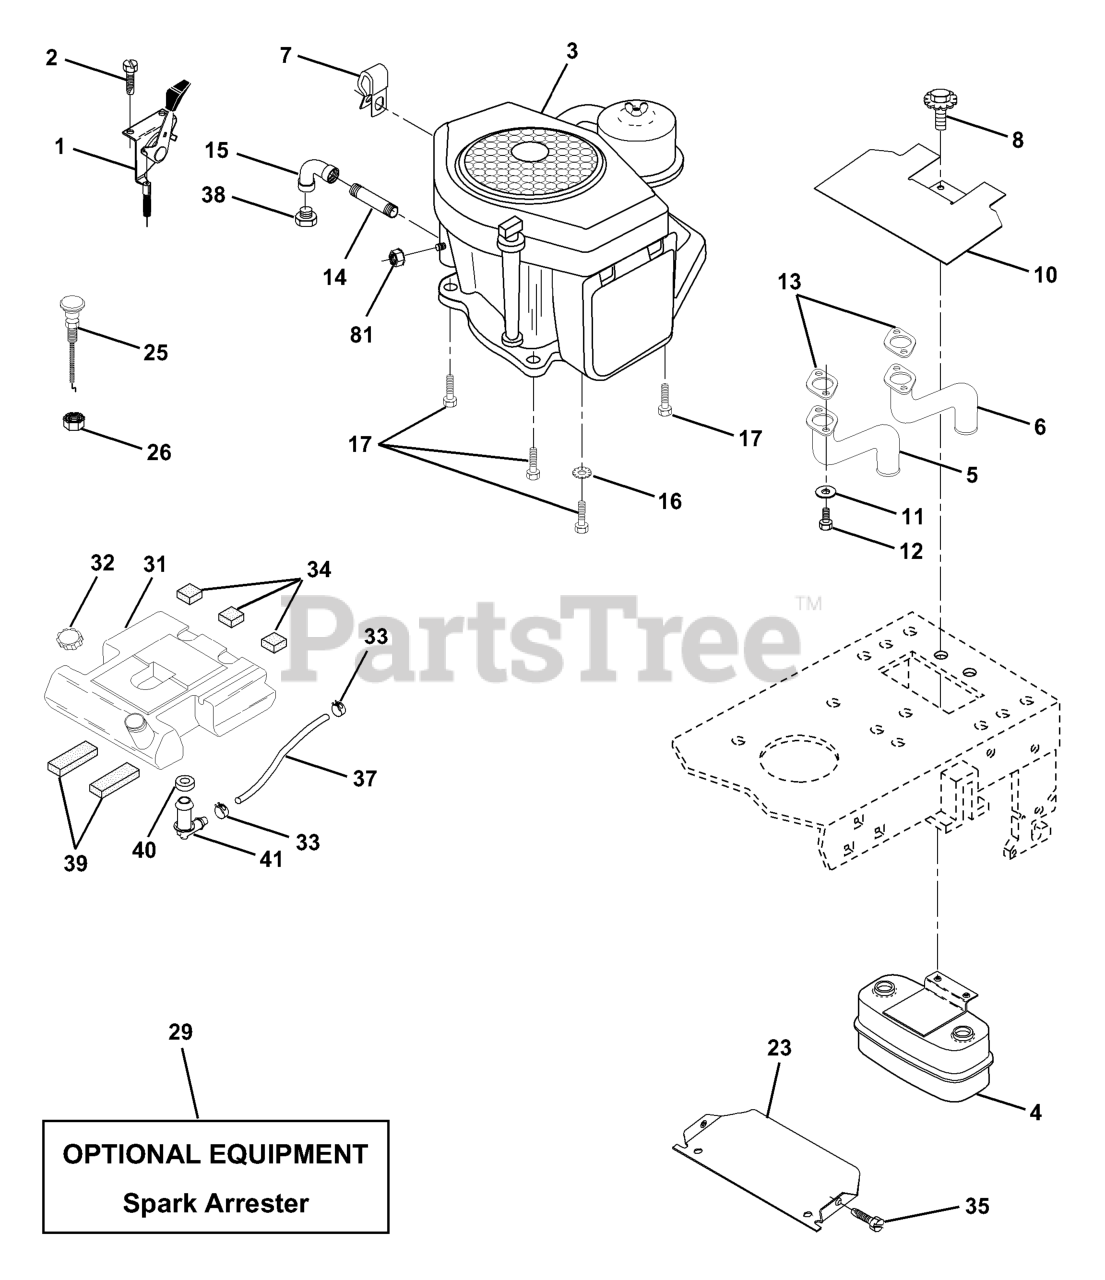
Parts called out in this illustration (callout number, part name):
1	CONTROL THROTTLE
2	SCREW LT
4	MUFFLER.TWIN.CYL.LOW.TONE
5	RP.PIPE-EXHAUST LH
6	RP.PIPE-EXHAUST RH
7	CLIP T
8	BOLT HEX WASHER HD 5/16-18
10	RP SHIELD HEAT MUFFLER
13	Muffler Gasket
14	Nipple Pipe 3/8 Npt X 4-1/2"
15	ELBOW
16	LOCKWASHER
17	SCREW LT
23	SHIELD HEAT
25	CONTROL, CHOKE
26	Nut, Keps 3/8-24 Unf
29	KIT.SPARK ARRESTOR 794945 B&S
31	FUEL TANK
32	FUEL CAP
33	HOSE CLAMP
34	PAD-SPACER LT
35	SCREW.THDROL.5/16-18X3/4.TTY
37	HOSE T
38	Plug Oil Drain
39	PAD IDLER TI
40	BUSHING OUTLET T
41	STEM FUEL TANK
81	NUT FLANGE 1/4-20 STARTER NUT
